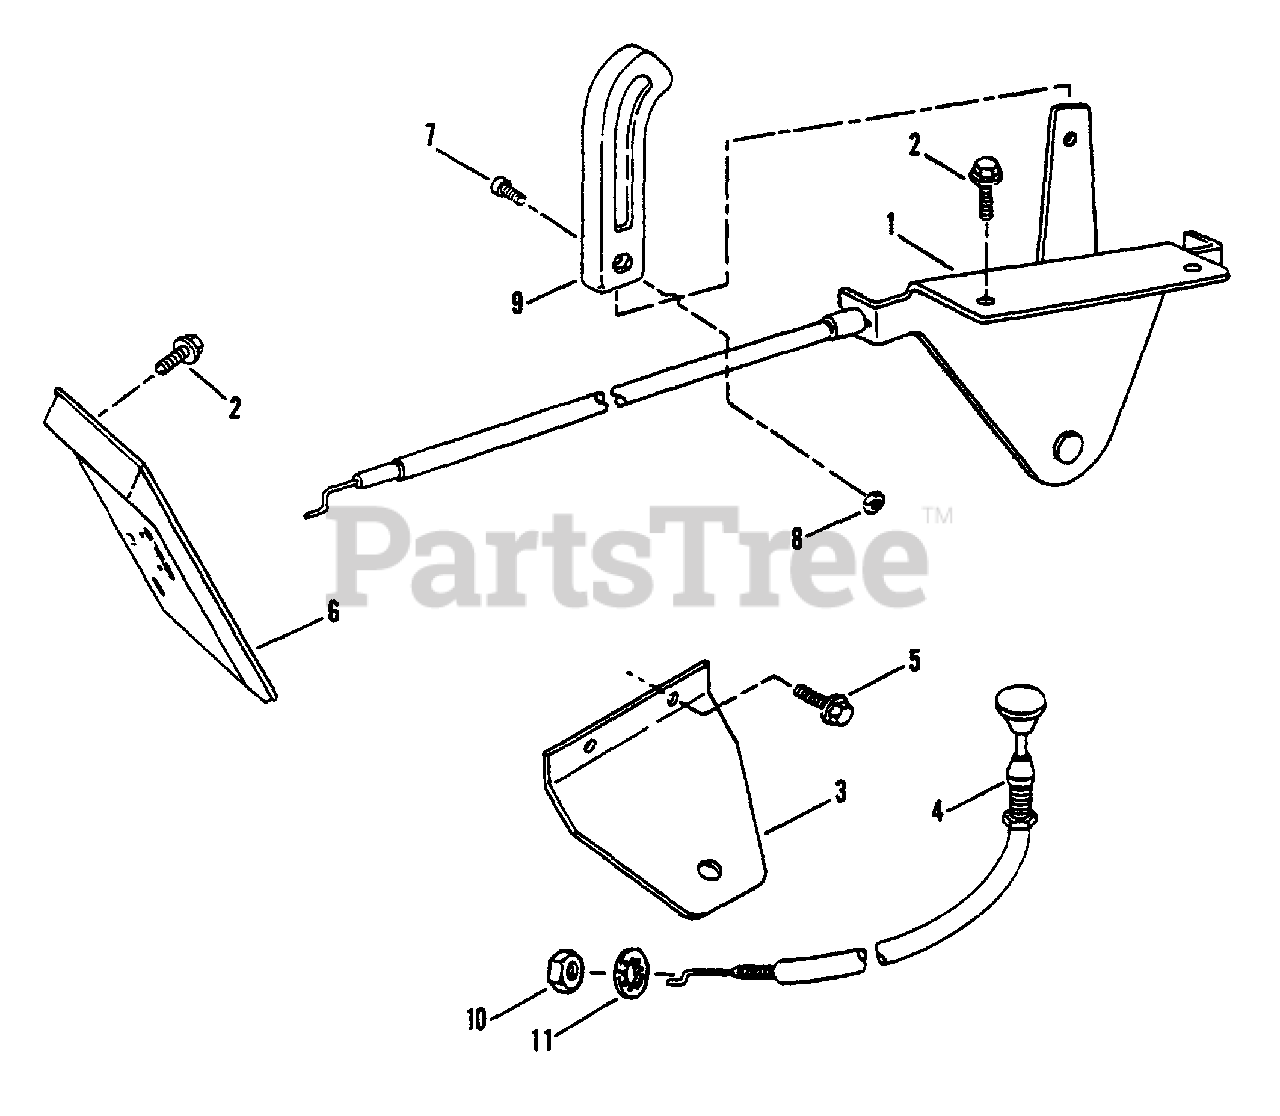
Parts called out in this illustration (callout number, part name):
1	CONTROL, Throttle (Briggs Engines)
2	SCREW, #10-24 x 1/2" Hex Washer Self-Tap (Torx)
3	PLATE, Throttle Control
4	CONTROL, Choke
5	SCREW, 1/4-20 x 5/8" Self-Tapping
6	COVER, Dash Panel
7	SCREW, #8-32 x 3/8" Cross-Recess, Fillister Head
8	NUT, 40-32 Hex
9	KNOB, Throttle Control
10	NUT, 3/8-24 Hex
11	WASHER, 3/8 Internal Tooth Lock
